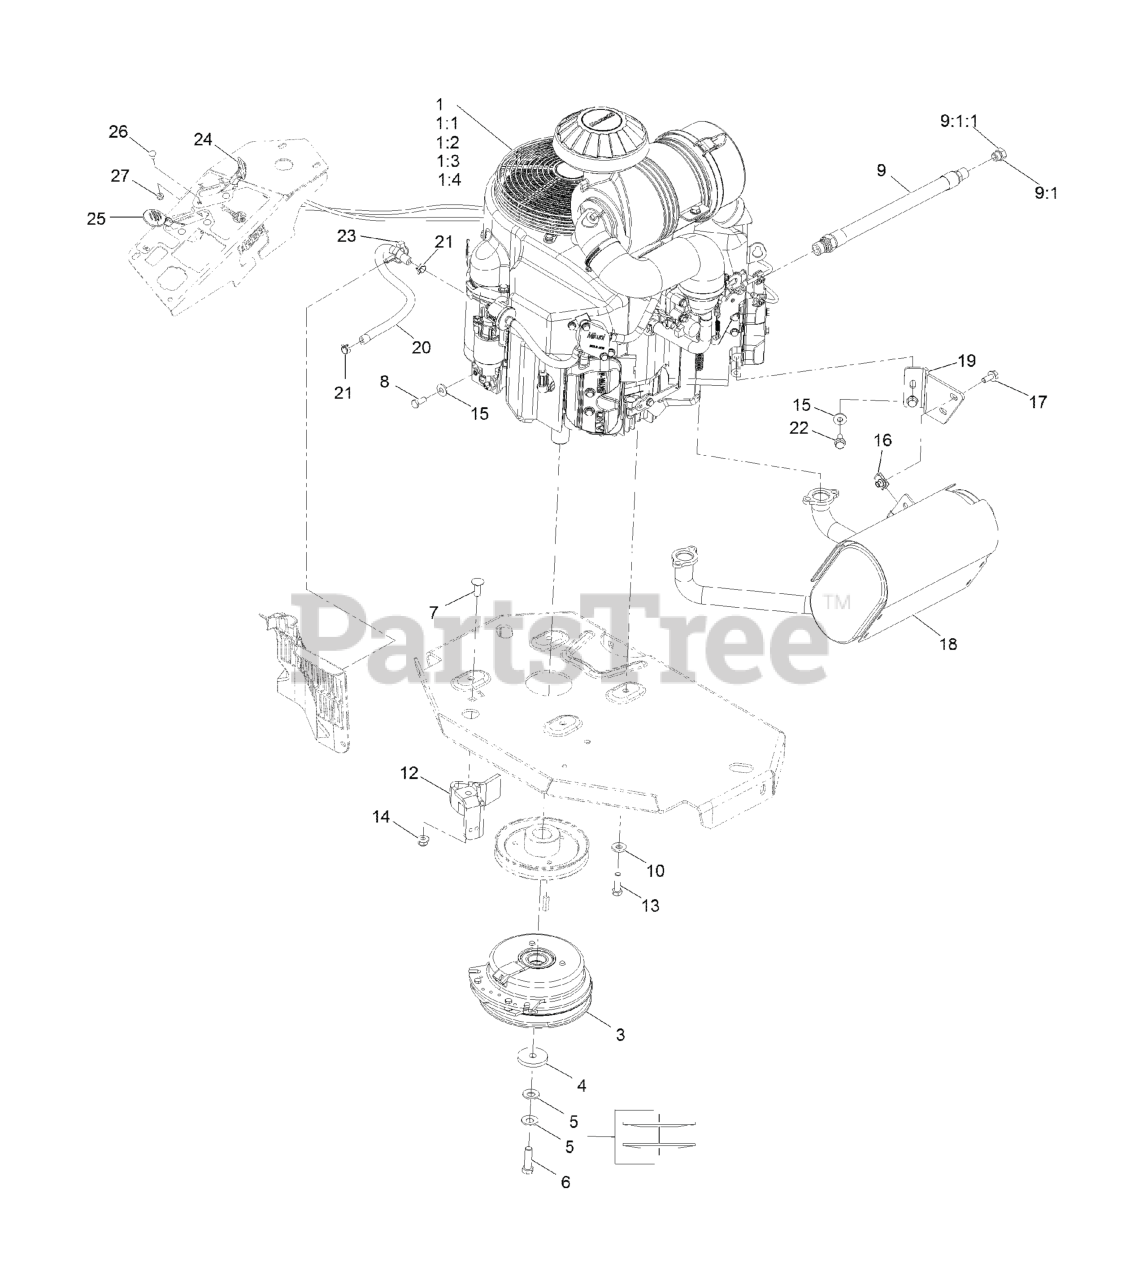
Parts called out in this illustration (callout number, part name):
1:1	Kawasaki 49065-2078 Engine Oil Filter
1:2	Kawasaki 49019-7001 Fuel Filter
1:3	Kawasaki 11013-7039 Safety Filter
1:4	Kawasaki 11013-7038 Air Filter
3	CLUTCH KIT
4	WASHER-CLUTCH
5	WASHER-SPRING
6	SCREW-HH 7/16-20 X 1 1/2 W/LOCTITE
7	SCREW-CARR
8	SCREW-HH
9	ENGINE OIL DRAIN HOSE ASM
9:1	PLUG-HH
9:1:1	O-RING
10	WASHER-BELLEVILLE
12	CLUTCH-ANCHOR
13	SCREW-HH
14	NUT-HF, NI
15	WASHER-SPRING
17	SCREW-HHF
18	MUFFLER
19	BRACKET-MUFFLER
20	HOSE-FUEL
21	CLAMP-HOSE
22	SCREW-HHF
23	CLAMP-HOSE
24	ASM, CHOKE CABLE
25	ASM,THROTTLE CABLE
26	BOLT-CARR
27	NUT-LOCK, NI
